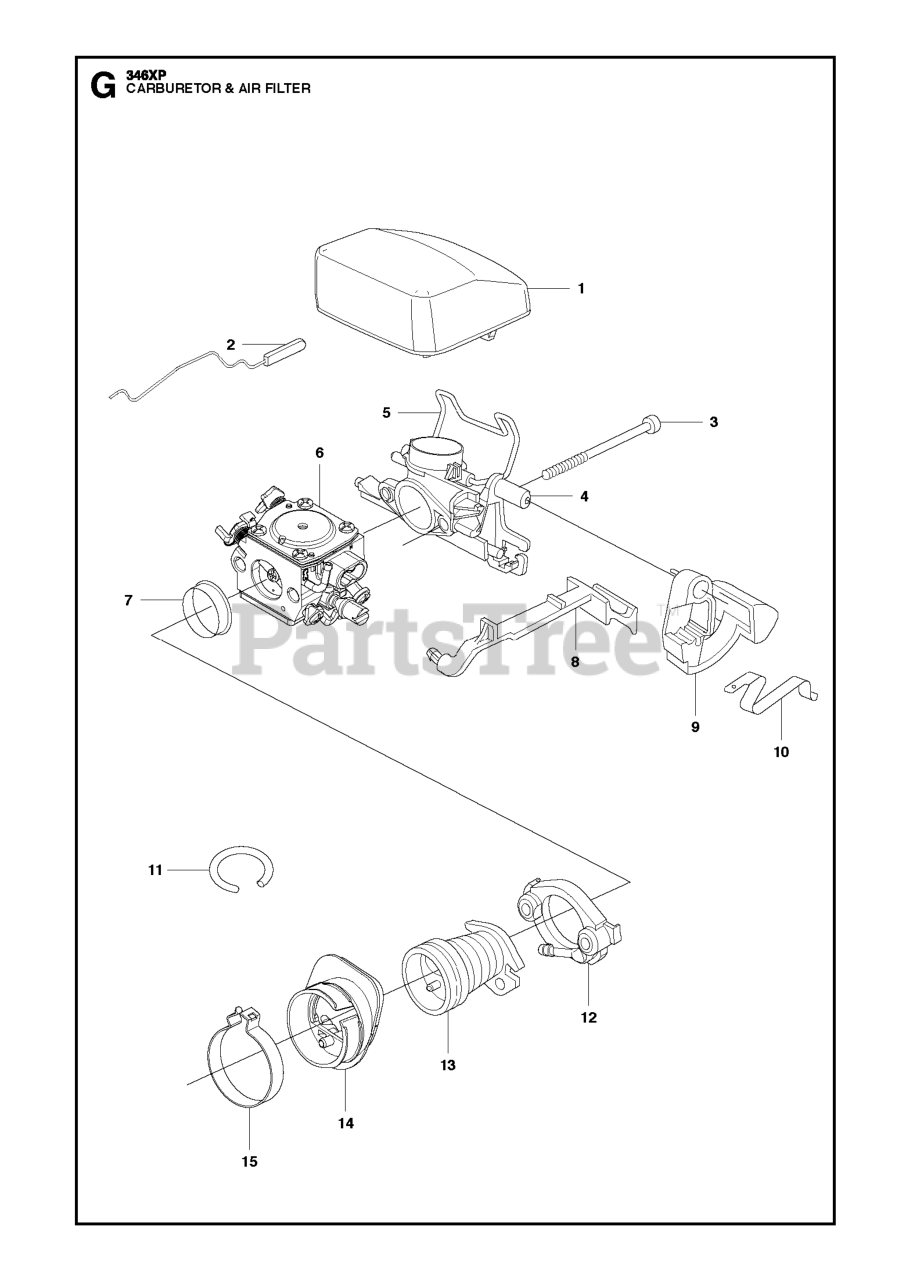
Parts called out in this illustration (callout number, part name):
1	AIR FILTER - FELT
1	AIR FILTER - NYLON (B)
1	AIR FILTER - NYLON (Y)
2	THROTTLE ROD
4	INTAKE BOOT
4	INLET ELBOW
5	FILTER CLAMP
6	CARBURETOR
8	CHOKE CONTROL
11	HOSE, IMPULSE
12	FLANGE
15	CLAMP, INTAKE
